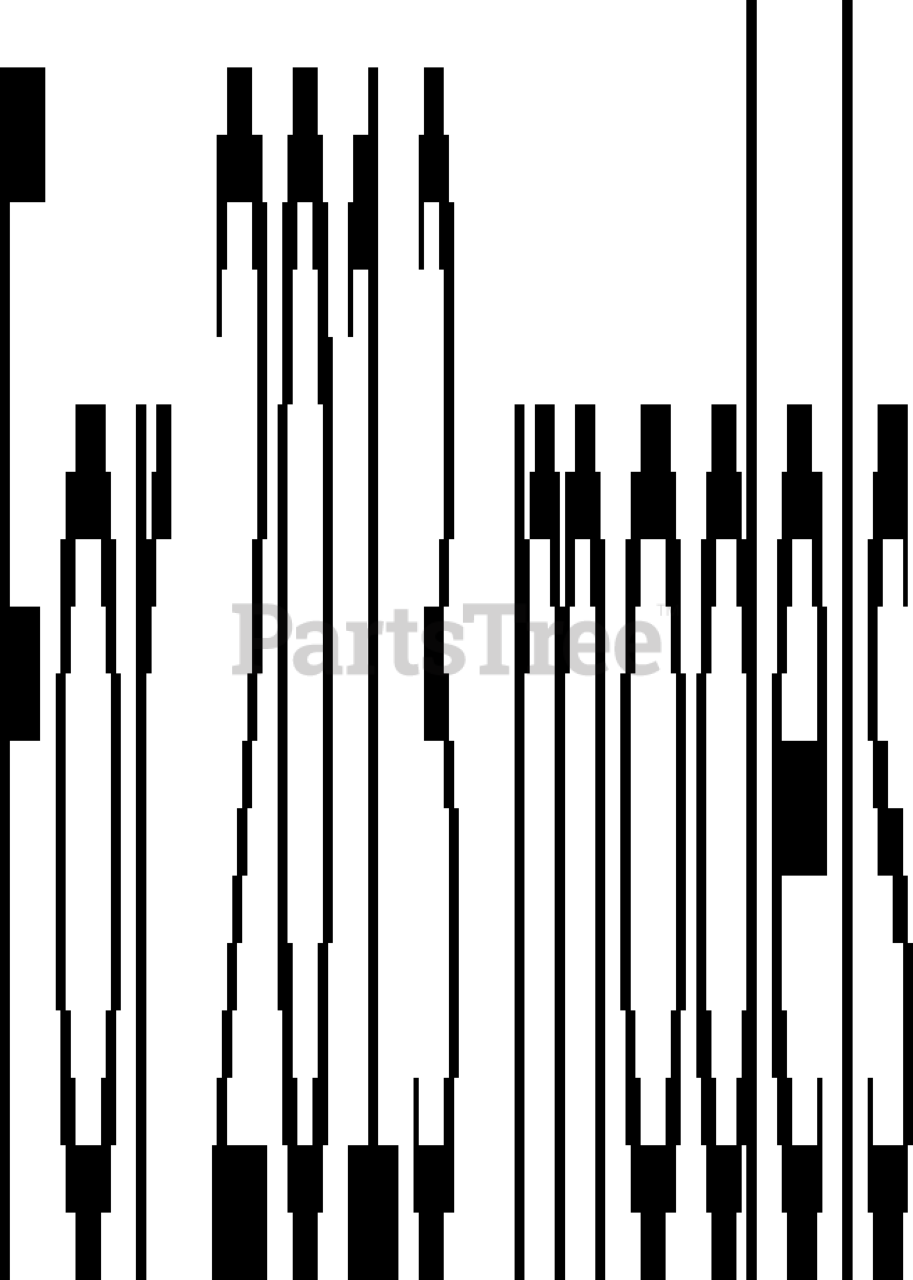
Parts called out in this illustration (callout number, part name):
5	WASHER 19X6X1
16	NUT FLANGE - M6
21	BALL BEARING 6201-2RS1
